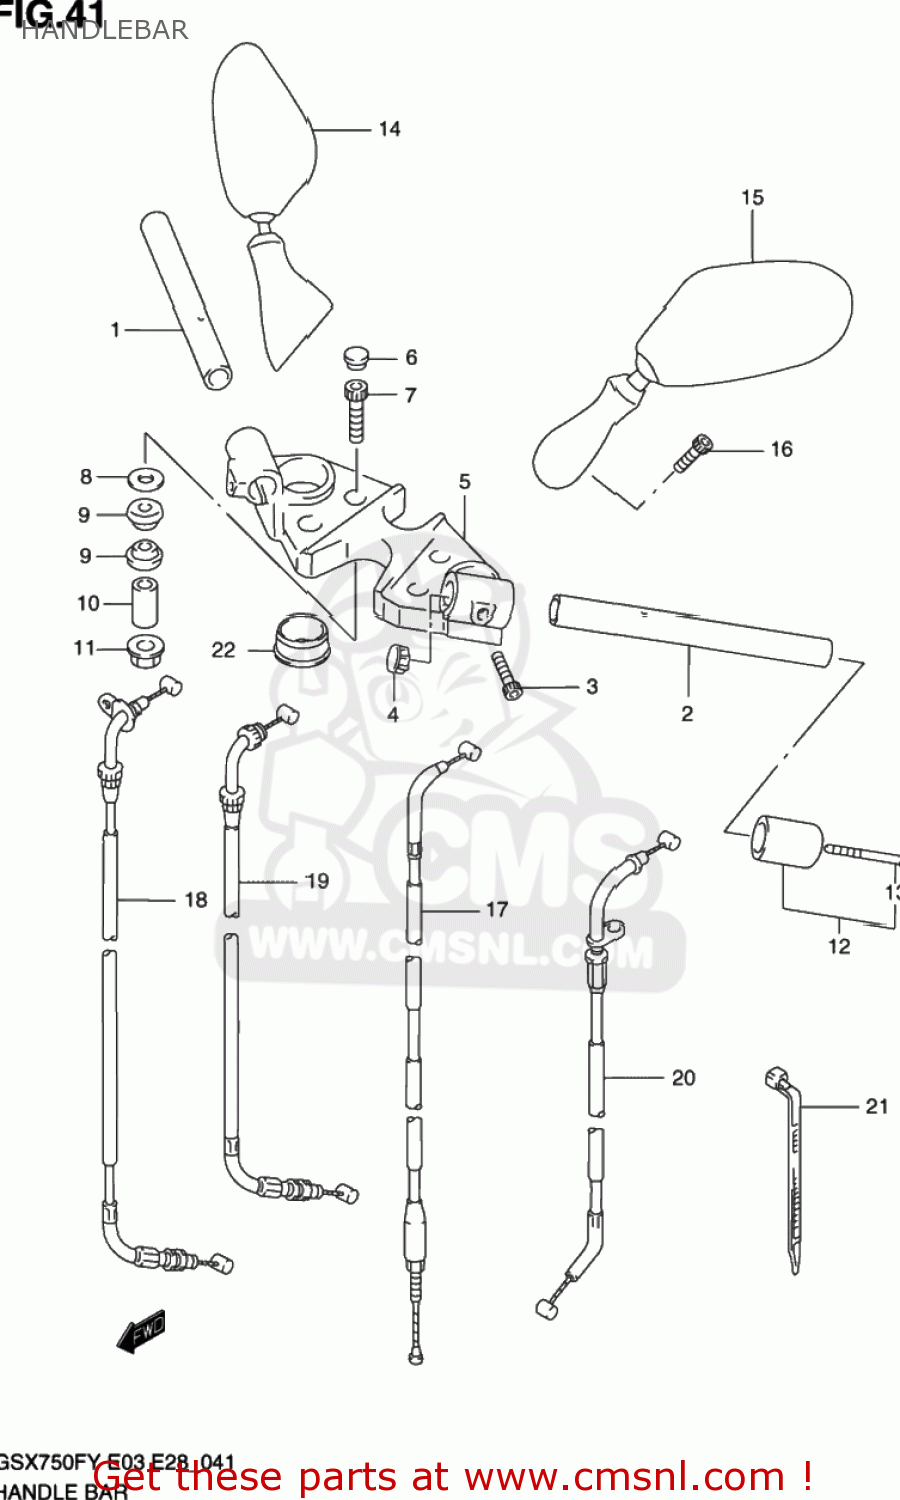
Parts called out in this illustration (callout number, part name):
1	HANDLEBAR,R
2	HANDLEBAR,L
3	BOLT
4	CAP,HANDLEBAR
5	HOLDER,HANDLEBAR
6	CAP(OD:12)
7	BOLT
8	WASHER(10.5X30X3.2)
9	CUSHION,UPR BRACKET
10	SPACER,HANDLEBAR BRACKET
11	NUT
12	BALANCER SET,HANDLEBAR
13	SCREW
14	MIRROR ASSEMBLY,REAR VIEW
15	MIRROR ASSEMBLY,REAR VIEW
16	BOLT,OIL FILLE
17	CABLE ASSY,CLUTCH
18	CABLE ASSY,THROTTLE NO.1
19	CABLE ASSY,THROTTLE NO.2
20	CABLE,STARTER
21	CLAMP(L:235)
22	CUSHION,HANDLE HOLDER
